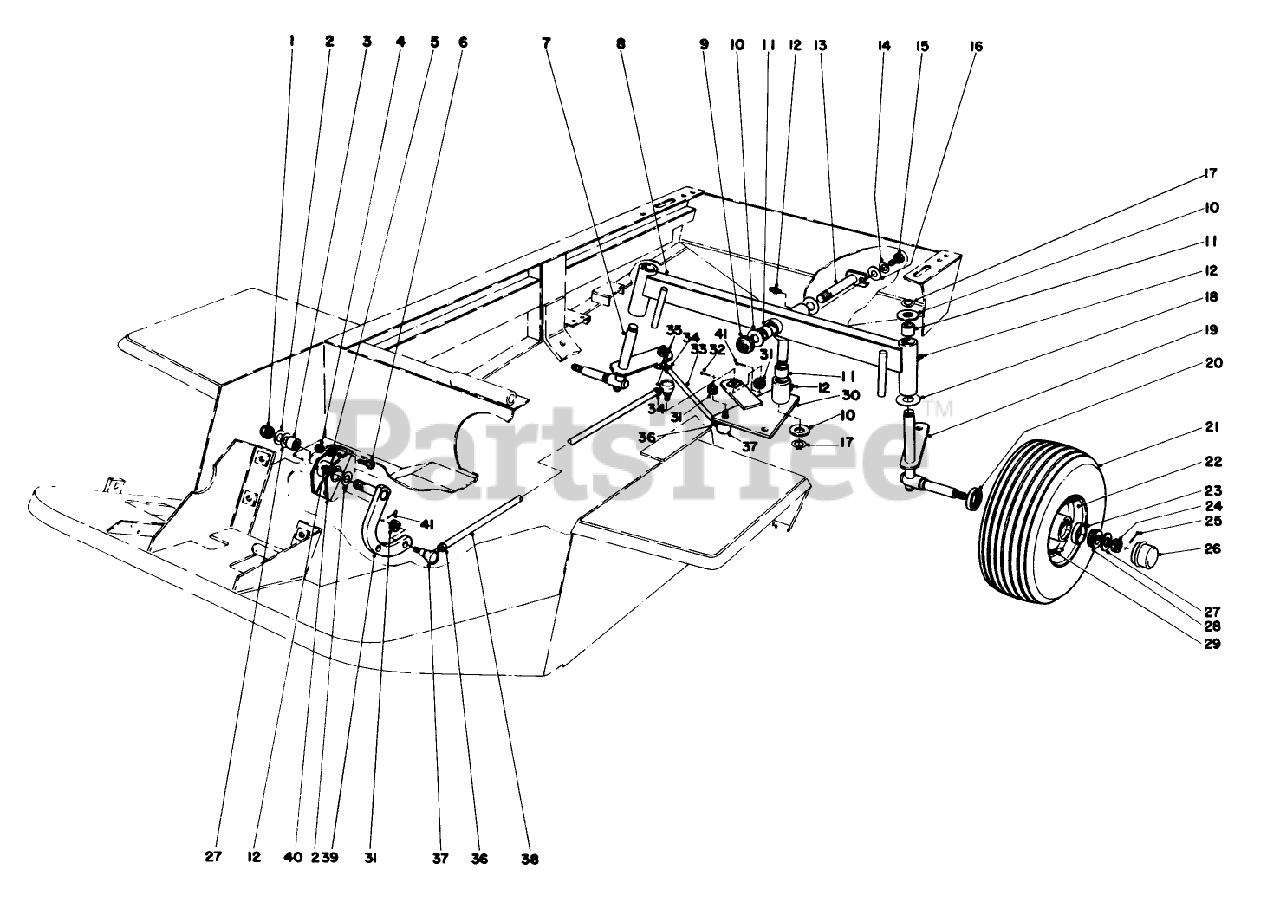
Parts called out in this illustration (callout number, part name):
1	NUT-LOCK, NI
2	THRUST WASHER
3	BEARING-NEEDLE
4	NUT-HEX
5	WASHER-LOCK
6	SCREW-HH
7	Spindle R.H.
8	Axle (Incl. Ref. #11 & 12)
9	NUT-LOCK, NI
10	WASHER-THRUST
11	BUSHING
12	FITTING-GREASE
13	Pin-RearAxle
14	WASHER-LOCK
15	SCREW-HH
16	WASHER-FLAT
17	RING-RETAINING
18	WASHER-THRUST
19	Spindle L.H.
21	Tire
22	Wheel (Incl. Ref. #23)
23	BEARING-CUP, TAPERED
24	NUT-HEX, SLOTTED
25	PIN-COTTER
26	CAP-DUST
27	WASHER-FLAT
28	BEARING-CONE, TAPERED
29	VALVE STEM AND CAP ASM
30	Steering Plate (Incl. Ref. #11 & 12)
31	NUT-SLOTTED
32	PIN-COTTER
33	Tie Rod Steering
34	NUT-HJ (LH THREAD)
35	Socket Assembly L.H. (Incl. Ref. #31)
36	NUT-JAM
37	Socket Assembly R.H. (Incl. Ref. #31)
38	REAR STRG TUBE PP
39	PIVOT ARM WA
40	Pivot Mount (Incl. Ref. #3 & 12)
41	PIN-COTTER
